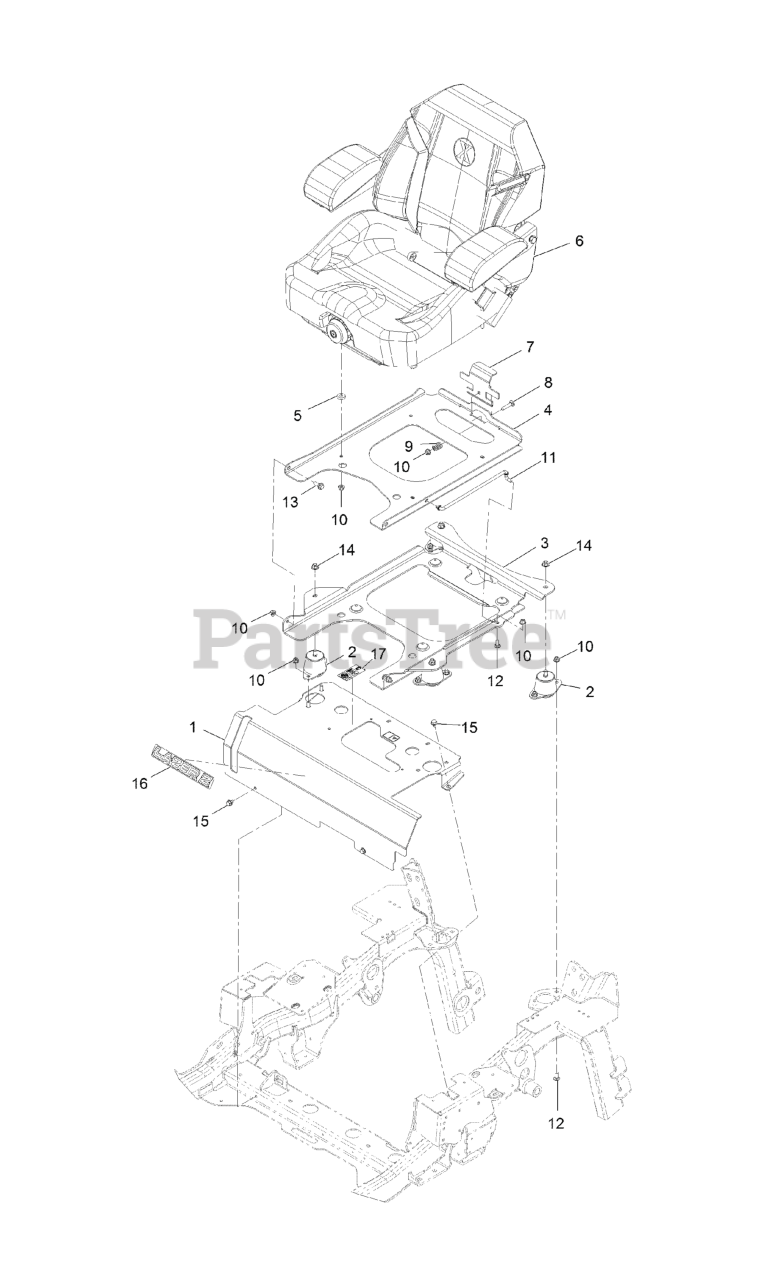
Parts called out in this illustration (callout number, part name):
1	SEAT MOUNT ASM
2	ISOLATOR-SEAT
3	PLATE-SUPPORT, TILT SEAT
4	PLATE-FRAME, SEAT
6	KIT-SUSPENSION SEAT
7	PLATE, SEAT LATCH
8	BOLT-CARR
9	SPRING-COMPRESSION
10	NUT-HF, NI
11	ROD-PROP
12	SCREW-CARR
13	SCREW-SHOULDER
14	NUT-HF, NI
16	DECAL, LAZER MODEL
17	DECAL-TRANS FLUID
